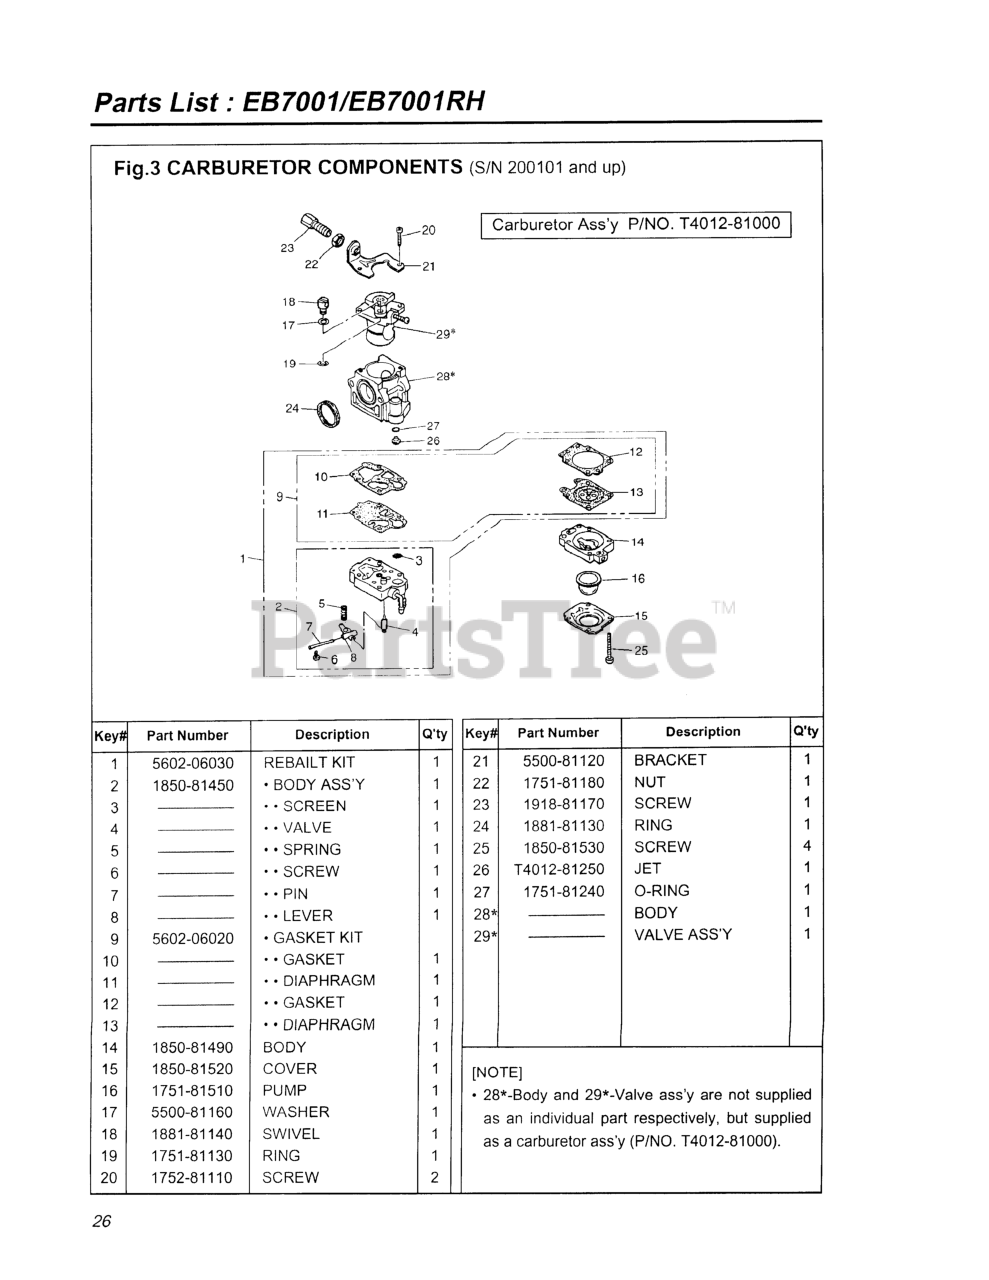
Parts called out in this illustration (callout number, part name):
2	BODY, PUMP
3	SCREEN
4	VALVE
5	SPRING
6	SCREW
7	PIN
8	LEVER
10	GASKET
11	DIAPHRAGM
12	GASKET
13	DIAPHRAGM
14	BODY, PURGE
15	COVER, PUMP
16	PUMP, PRIMING
17	WASHER
18	SWIVEL
19	RING
20	SCREW
22	NUT, CABLE ADJUSTER
23	SCREW, CABLE ADJUSTER
24	RING, PACKING
25	SCREW
26	JET
27	RING, O
28	CARBURETOR (WYK-123-1)
29	CARBURETOR (WYK-123-1)
NI	CARBURETOR (WYK-123-1)
